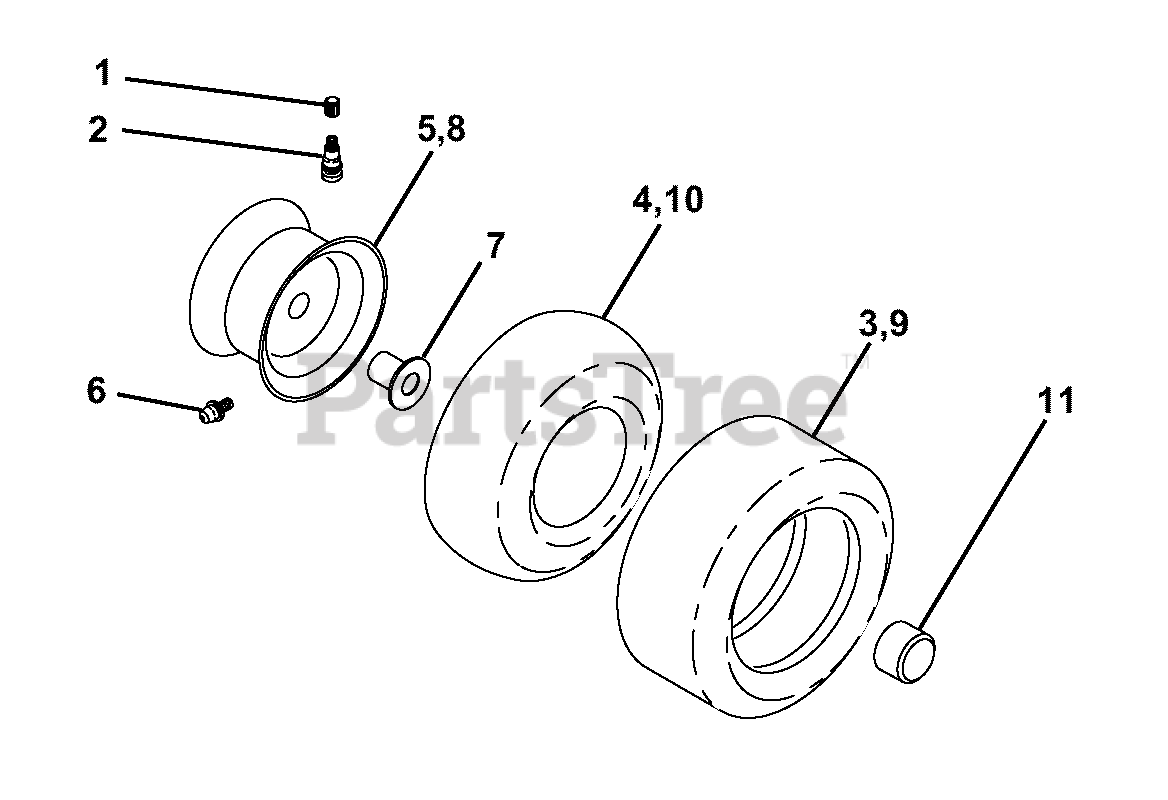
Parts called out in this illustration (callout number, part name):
1	Cap Valve Tire
2	Stem Valve
3	Tire F Ts 15 X 6 0 - 6 Service
4	Tube Front
5	Rim Asm 6"front White Service
6	Fitting Grease
7	Bearing Flange
8	Rim Asm 8" rear White Service
9	Tire R Ts 18x9.5-8 C Service
10	Tube Rear
11	Cap Axle Blk 1 50 X 1 00
